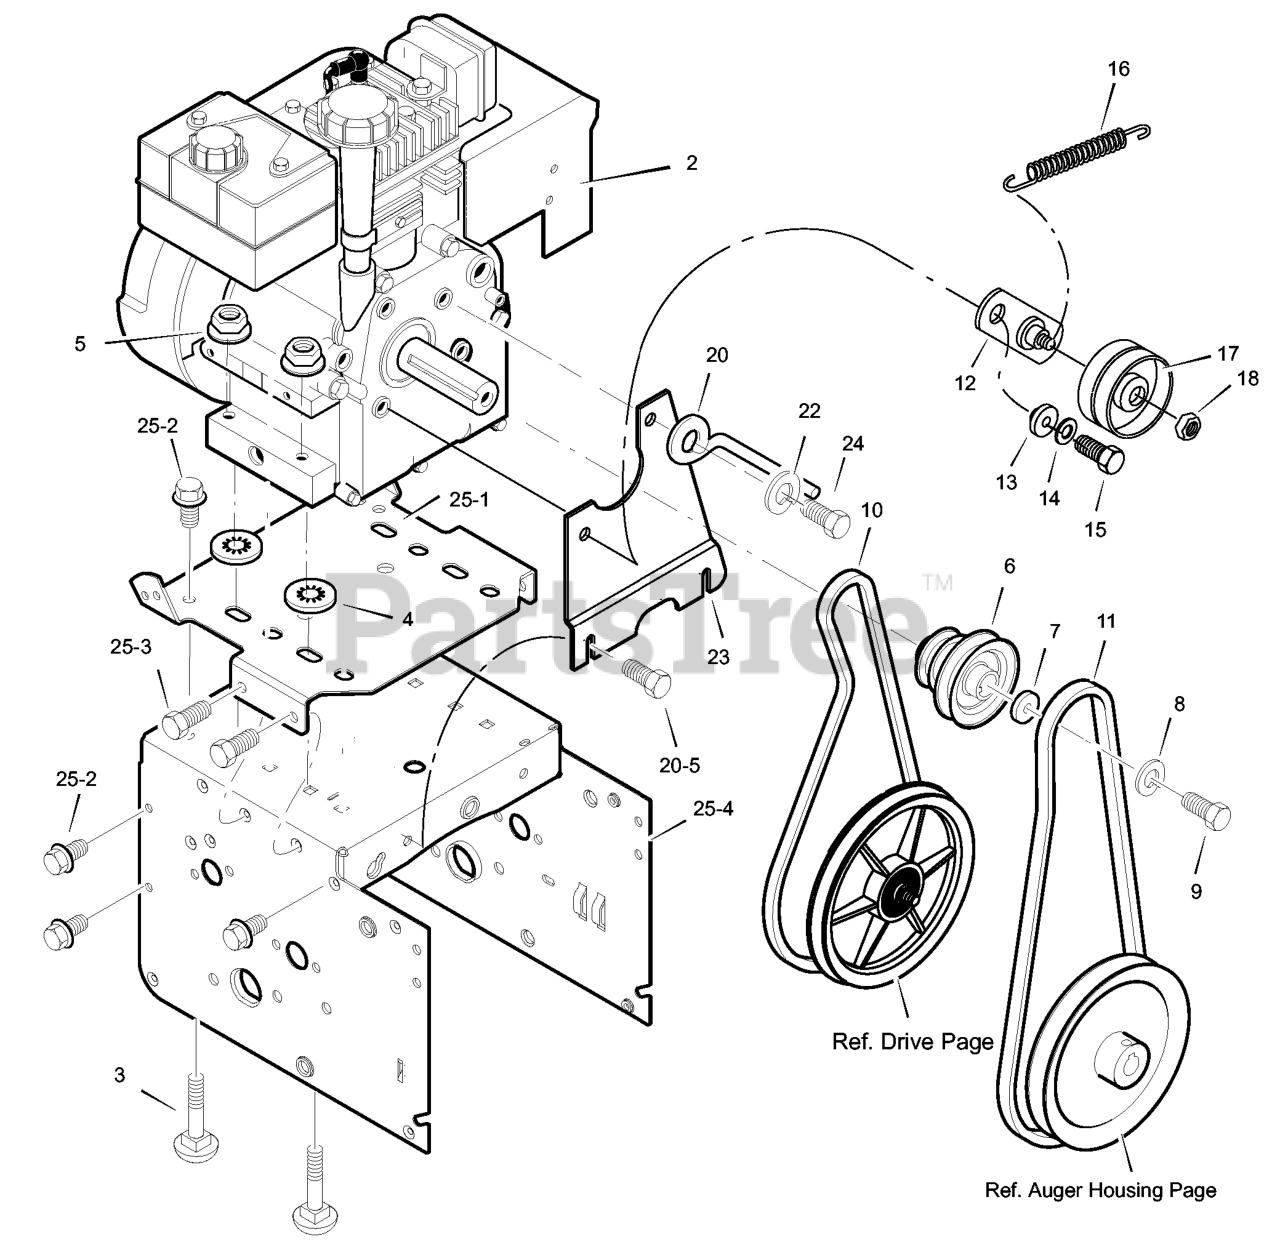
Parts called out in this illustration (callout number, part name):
2	ENGINE
3	BOLT, CARRIAGE 5/16-18
4	RETAINER, PUSH
5	NUT, HEX 5/16-18
6	PULLEY, ENGINE
7	WASHER
8	WASHER .38ID
9	SCREW, 3/8-24 x 1.00
10	BELT, DRIVE V 3L
11	BELT, AUGER V 4L
12	BRACKET ASSEMBLY, IDLER
13	BUSHING, IDLER BRACKET
14	WASHER, SPLIT
15	SCREW 5/16-24 X 1.00
16	SPRING, IDLER TRACTION DRIVE
17	PULLEY, IDLER
18	NUT, JAM 3/8-16
20	GUIDE, BELT
22	WASHER, SPTLK .31X.58X.08
23	PLATE, ANTI VIBRATION
24	SCREW, 5/16-24 x 1.00
25	FRAME ASSEMBLY
25-1	PLATE, ENGINE MOUNT
25-2	SCREW, TAP 1/4-20 X .63
25-3	SCREW, TAP 5/16-18 X .50
25-4	FRAME, MOTOR BOX
